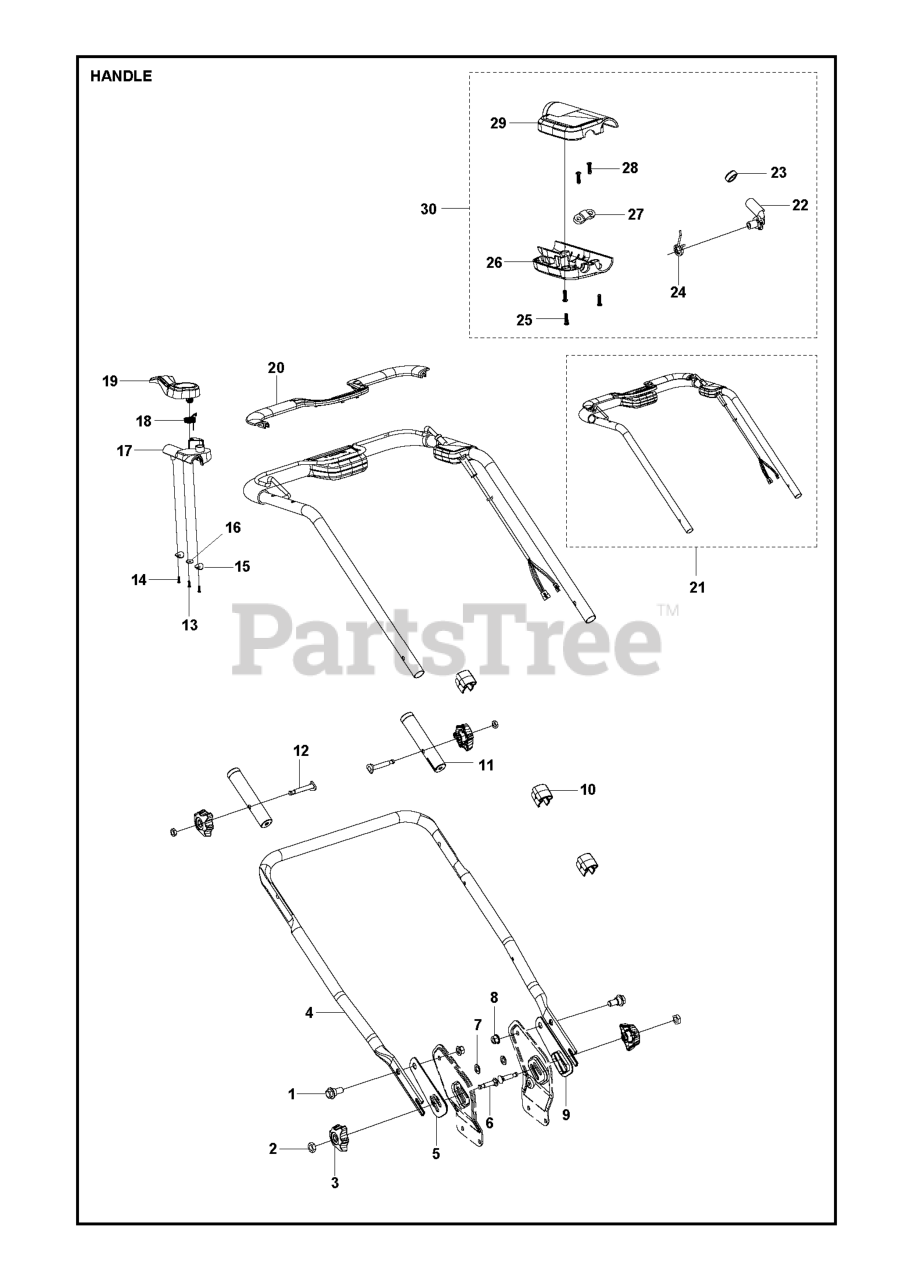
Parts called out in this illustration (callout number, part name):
2	HEXAGON NUT #26800502301
3	KNOB #25341500101
4	HANDLEBAR LOWER
5	PLATE RIGHT
7	SPACER RING
8	LOCKING BOLT M8,GB6187.1 #2680
9	PLATE LEFT
10	HOLDER CABLE
17	HOLDER BAIL STOP SOLUTION HOLD
18	TORSION SPRING
19	COVER BAIL STOP SOLUTION
20	COVER BAIL ARM COVER
21	HANDLE KIT DAYE# 90000305401
30	SWITCH KIT
